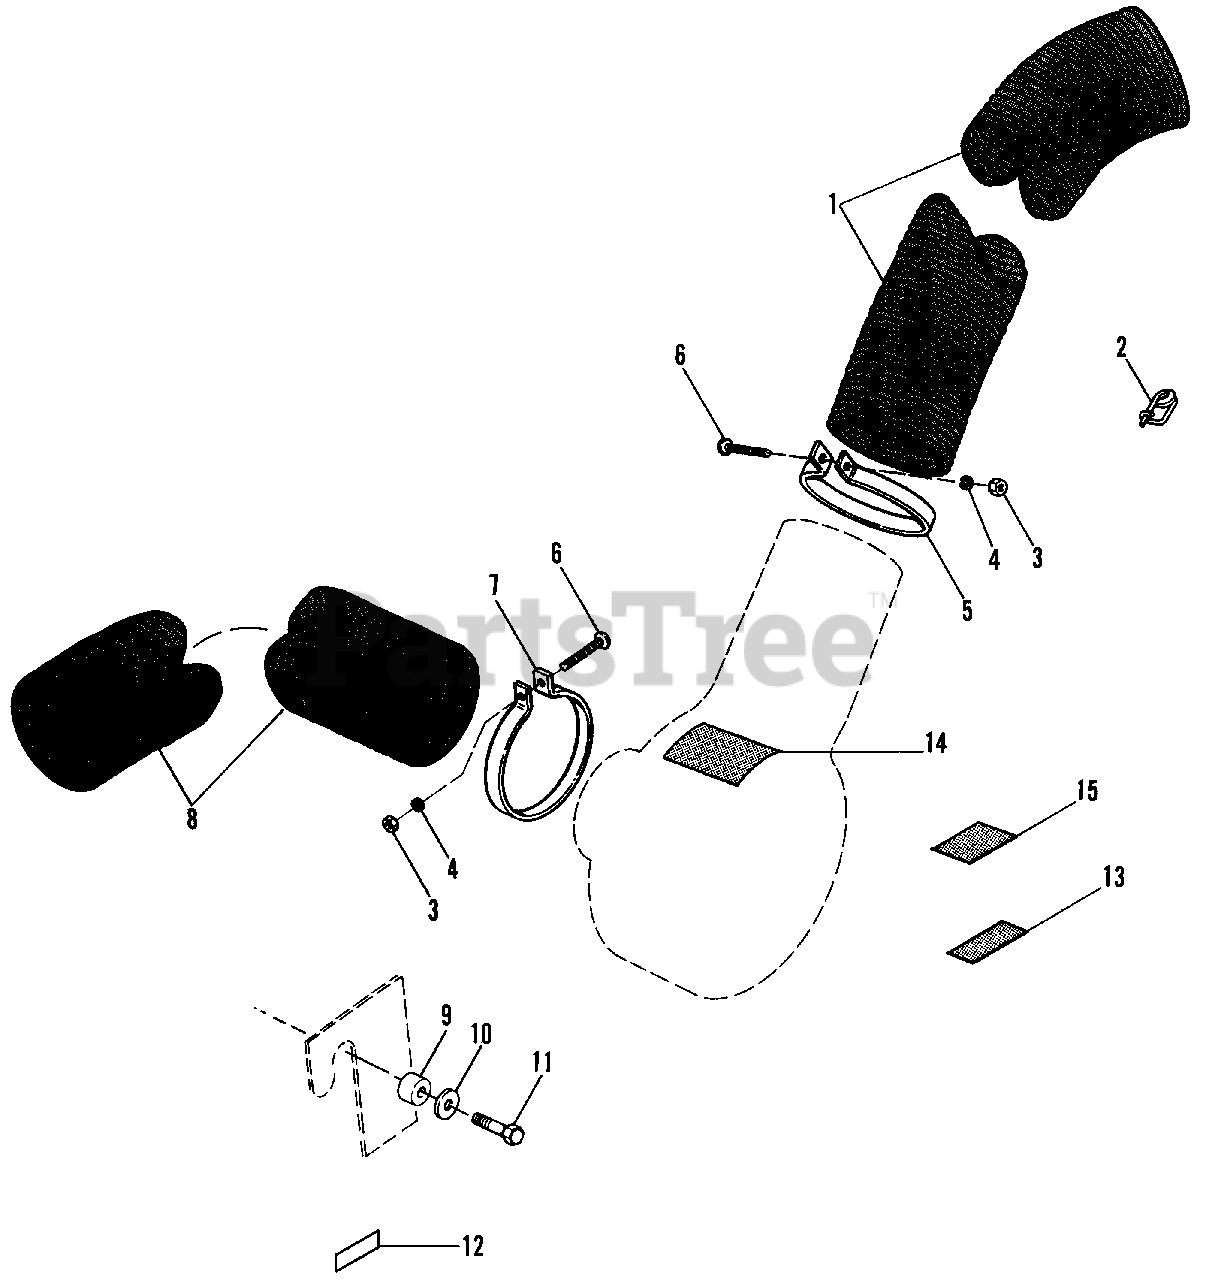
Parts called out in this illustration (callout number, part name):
1	HOSE ASSY., Outlet, 6" Dia.
2	CLIP, Pin, Safety
3	NUT, Hex, 1/4-20
4	LOCKWASHER, Spring, 1/4
5	CLAMP, Hose, 6"
6	SCREW, Rd. Hd., 1/4-20 x 3
7	CLAMP, Hose, 7"
8	HOSE ASSY., Inlet, 7" Dia.
10	WASHER, Plain, 3/8
11	CAPSCREW, Hex Hd., 3/8-16 x 1-1/4
12	PLATE, I.D.
13	DECAL, Throttle
14	DECAL, Warning
15	DECAL, Muffler
